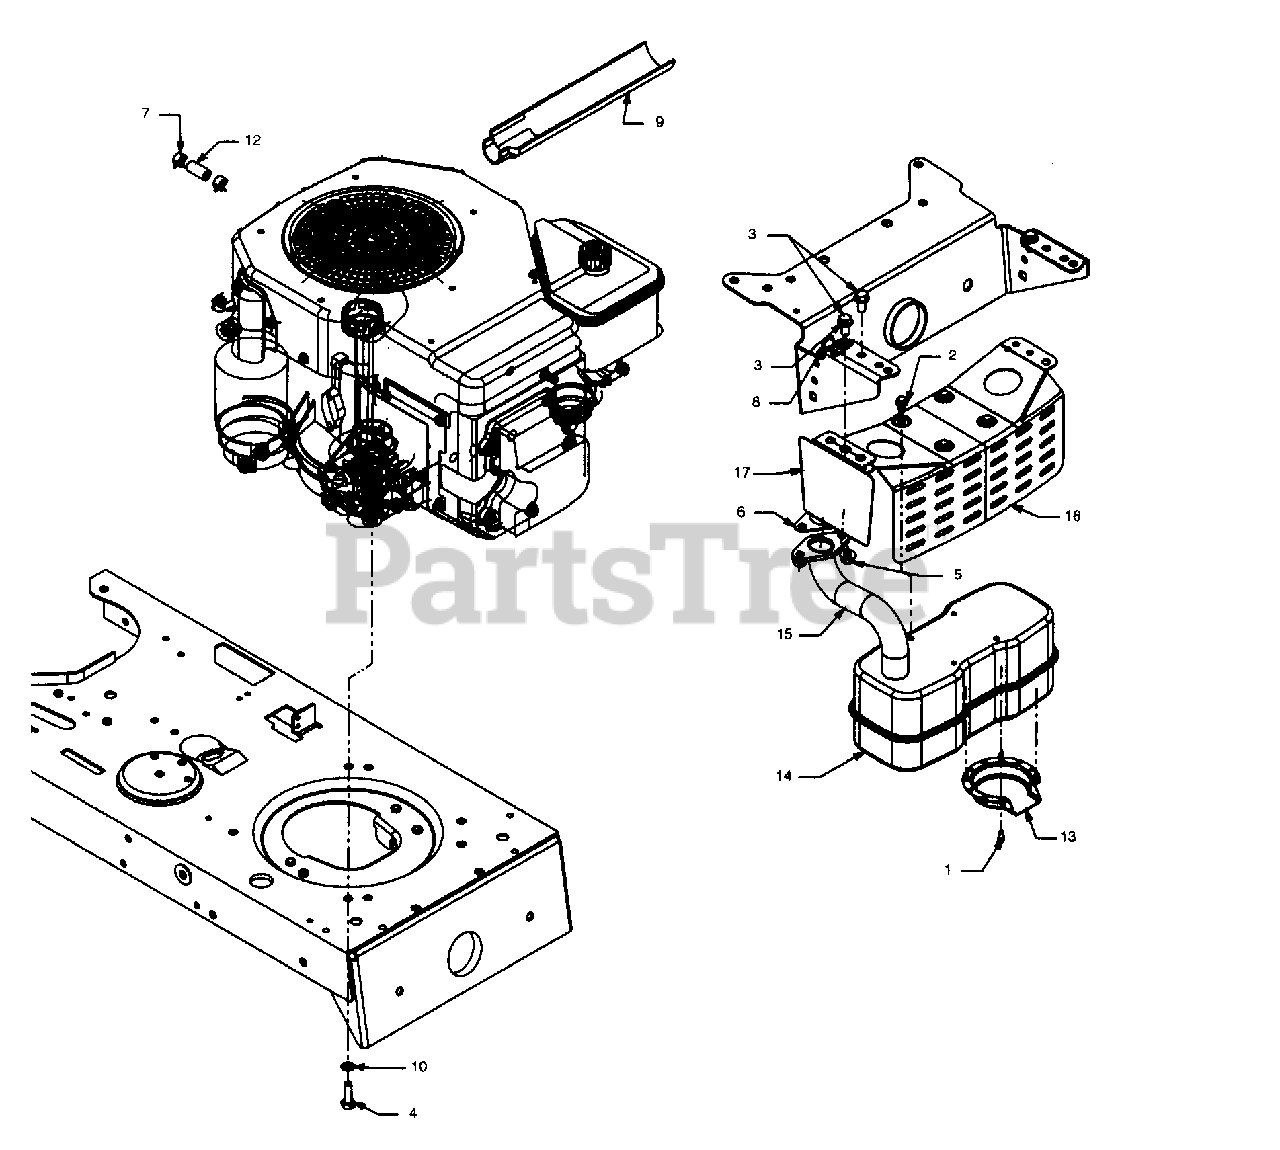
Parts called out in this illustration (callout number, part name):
1	Hex Tap Scr. #8-32 x .38" Lg.
2	Hex Wash. TT-Tap Scr. 1/4-20x5" Lg.
3	Hex Wash. TT-Tap Scr. 5/16-18 x .62" Lg.
4	Hex Bolt M8 x 1.25
5	Hex Flange Nut M8 Thd.
6	Exhaust Gasket
7	Hose Clamp
8	Clamp
9	Oil Drain Sleeve
10	External L-Wash. 5/16" I.D.
12	Fuel Line 12" Lg.
13	Muffler Deflector
14	Muffler
15	Exhaust Pipe
16	Muffler Bracket
17	Shield Bracket.
